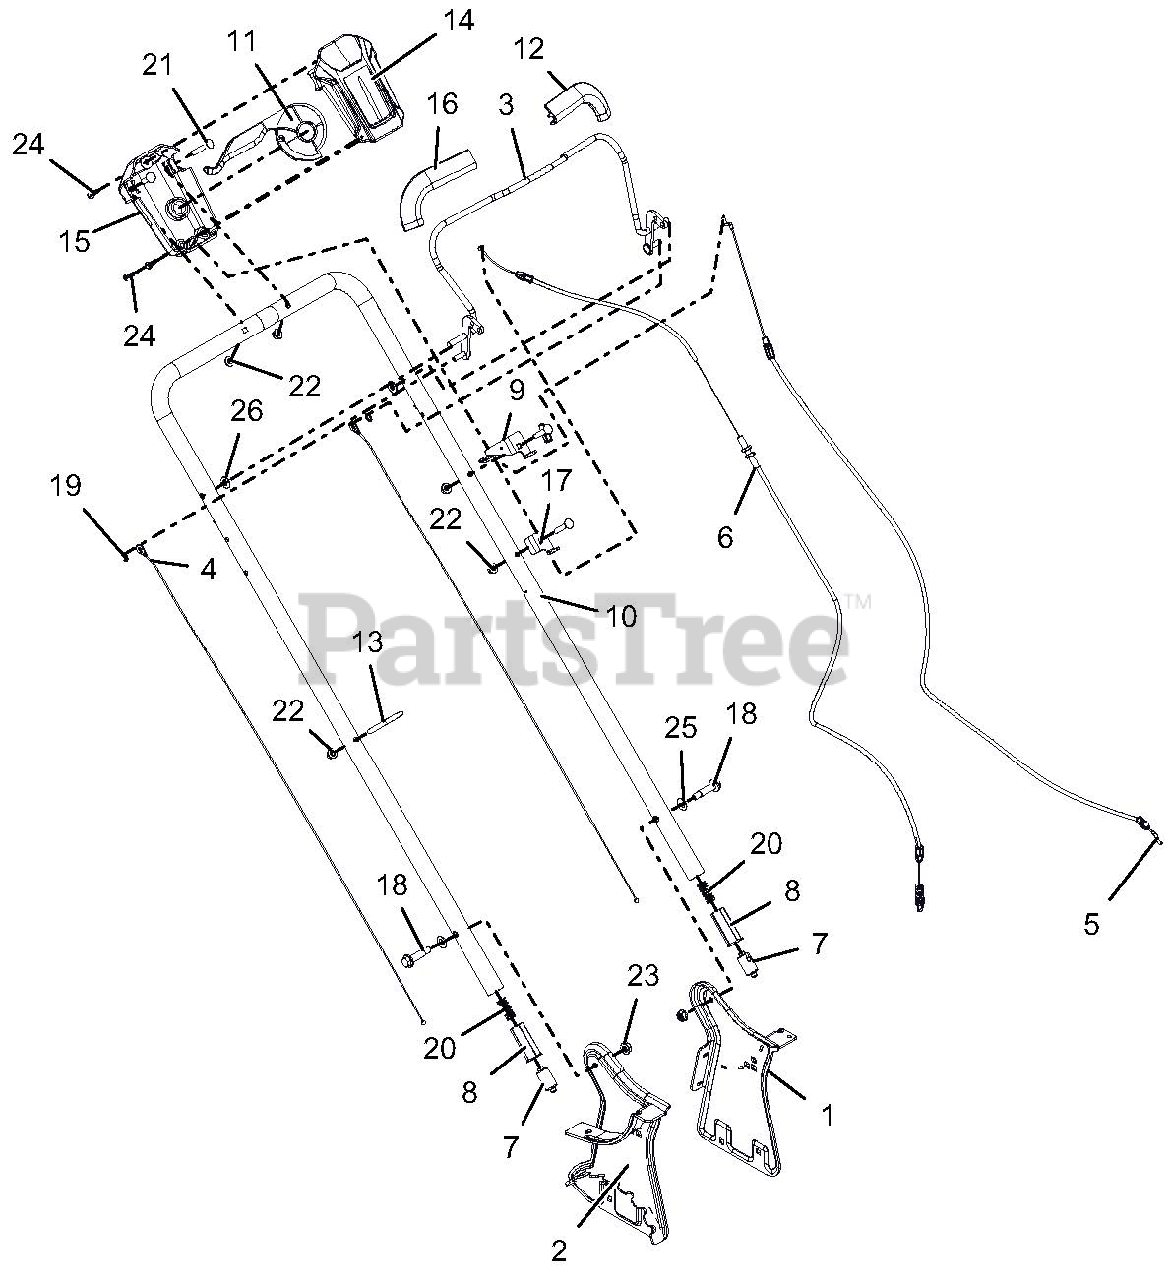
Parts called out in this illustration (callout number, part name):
1	SUPPORT, LH HANDLEBAR
2	SUPPORT, RH HANDLEBAR
3	WLDMT, OPC BAIL
4	CABLE, LM HANDLE ADJUST
5	CABLE, OPC, RAZOR LM
6	CABLE, DRIVE CONTROL
7	PLUNGER, HANDLEBAR LOCKING
8	INSERT, HANDLEBAR ADJUST
9	BRKT, CABLE ANCHOR
10	HANDLEBAR, LM
11	HANDLE, DRIVE CONTROL
12	GUARD, FINGER - LH
13	HOLDER, RECOIL CORD
14	HOUSING, UPPER DRIVE CONTROL
15	HOUSING, LOWER DRIVE CONTROL
16	HAND GRIP W/ DECAL
17	BRKT, CABLE - DRIVE
18	BLT-SHLDR, .50X1.15X.312-18GR5
19	RG-RTNG-EXT .250X.010
20	SPRING, COMPRESSION
21	@BLT-RDHDSQNK .25-20X1.50 G5YZ
22	@NUT-LK-TOP-FLG .25-20 YWZC
23	@NUT-LK-TOP-FLG .31-18 YWZC
24	SCR-TAP 12-14X.75PLSTITE @BLZC
25	WSHR,.385X.745X.030 STL YWZC
26	@WSHR-FL-STL.344X.688X.065YWZC
